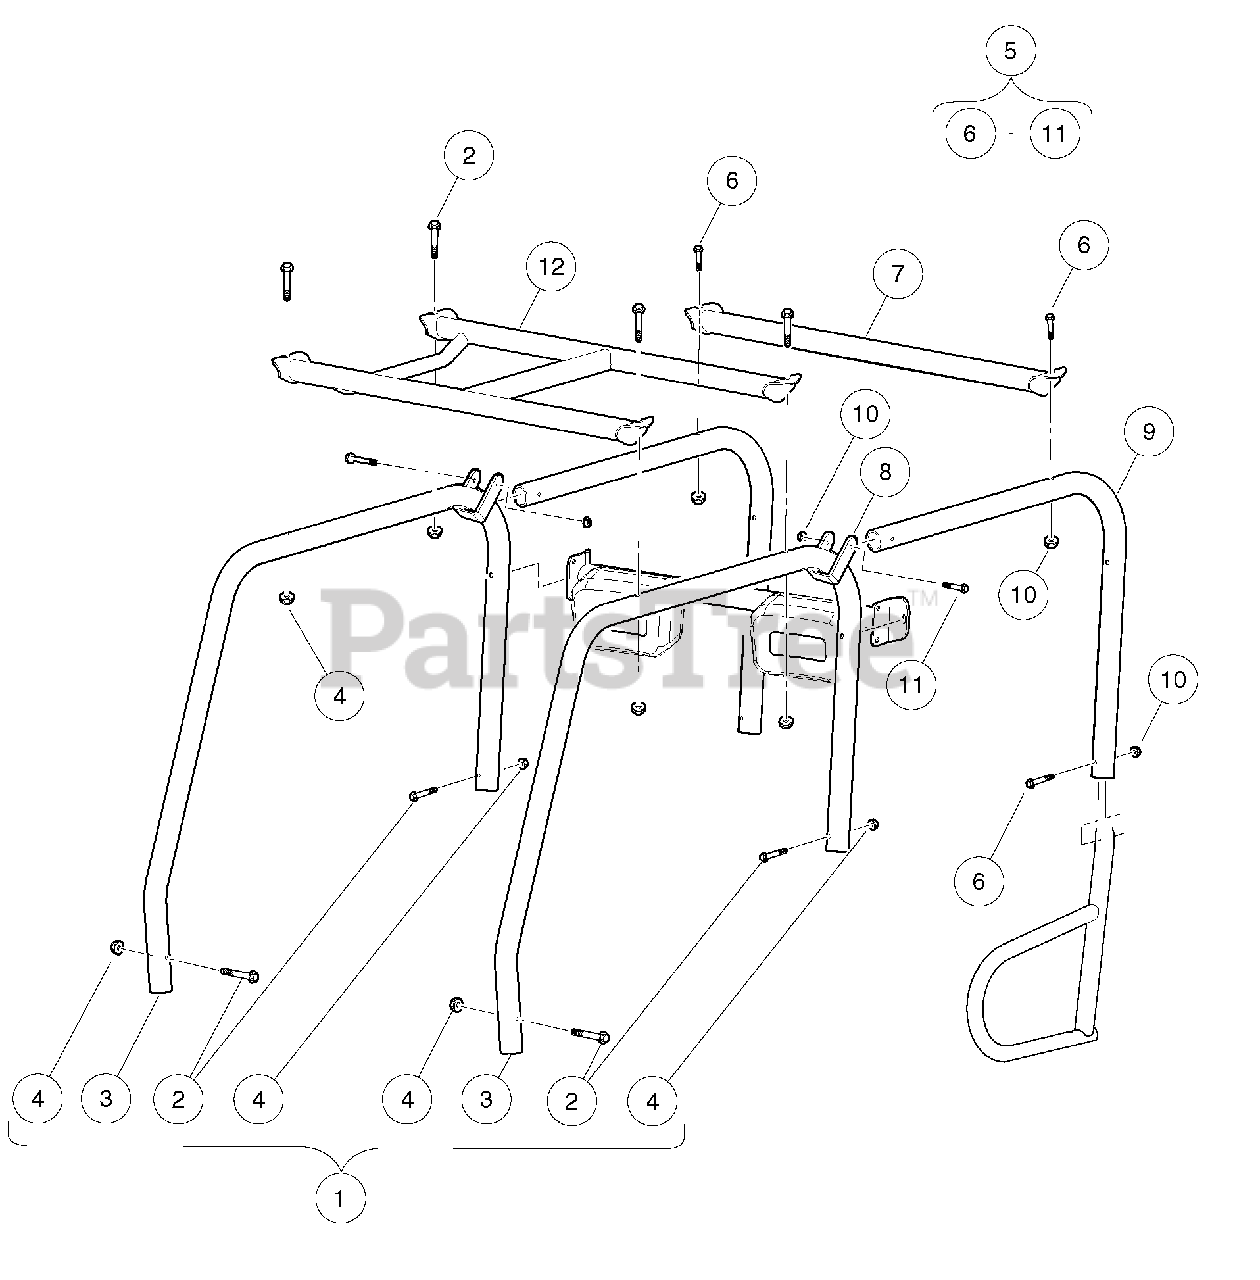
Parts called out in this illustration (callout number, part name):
1	Kit, ROPS, Domestic
2	Bolt, Flanged, M10 X 1.5 X 65
3	Tube, Side Support Short, ROPS
4	Nut, Flanged, M10 x 1.5, Black
5	Kit, ROPS, Four Passenger
6	Bolt, Flanged, M10 X 1.5 X 65
7	Weldment, ROPS, Top, 4 Pass
8	Bracket, ROPS, Rear, 4 Pass
9	Tube, Rear, 4 Pass
10	Nut, Flanged, M10 x 1.5, Black
11	Bolt, Flanged, M10 X 1.5 X 70
12	Asm, Top, ROPS
